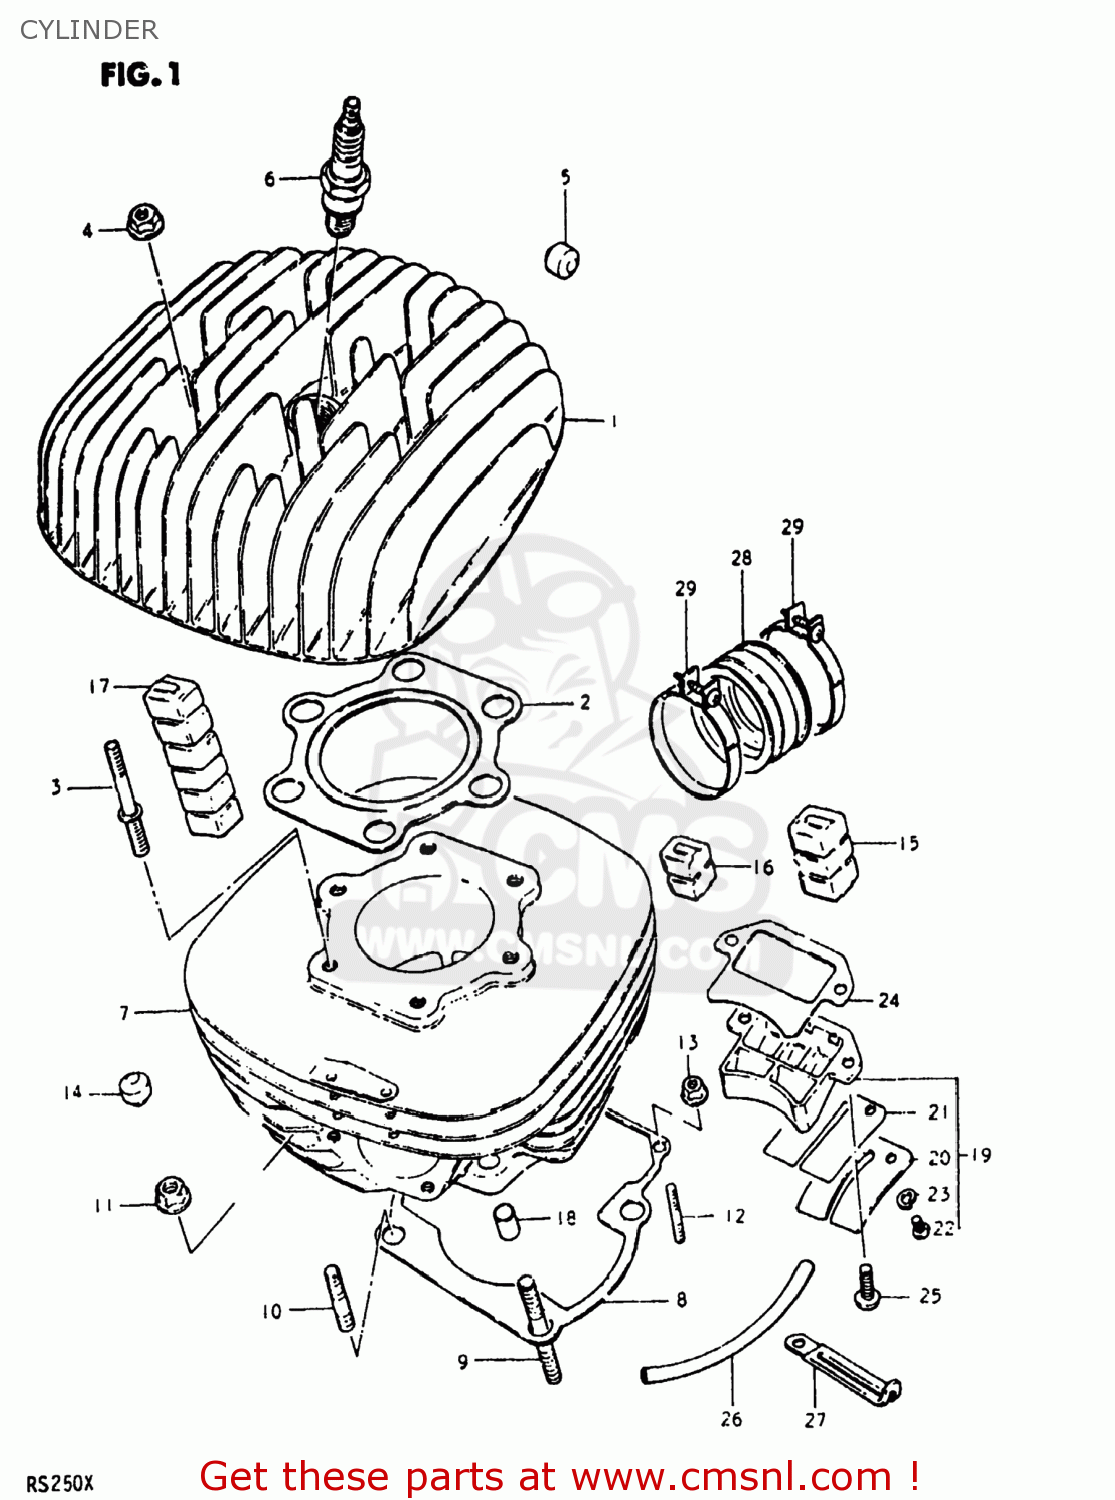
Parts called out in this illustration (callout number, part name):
1	HEAD,CYLINDER
2	GASKET,CYLINDER HEAD (NAS)
3	BOLT,STUD
4	NUT
5	PAD,CYLINDER HEAD
6	SPARK PLUG
7	CYLINDER
8	GASKET,CYLINDER (MCA)
9	STUD BOLT (L:40)
10	STUD 10X25
11	NUT
12	STUD 6X20
13	NUT
14	PAD,CYLINDER HEAD
15	PAD,CYLINDER
16	PAD,CYLINDER
17	PAD,CYLINDER
18	PIN
19	VALVE ASSEMBLY,REED
20	STOPPER,REED VALVE
21	VALVE,REED
22	SCREW
23	LOCK WASHER
24	GASKET,REED VALVE (MCA)
25	SCREW
26	HOSE
27	CLAMP
28	PIPE,INTAKE
29	CLAMP
